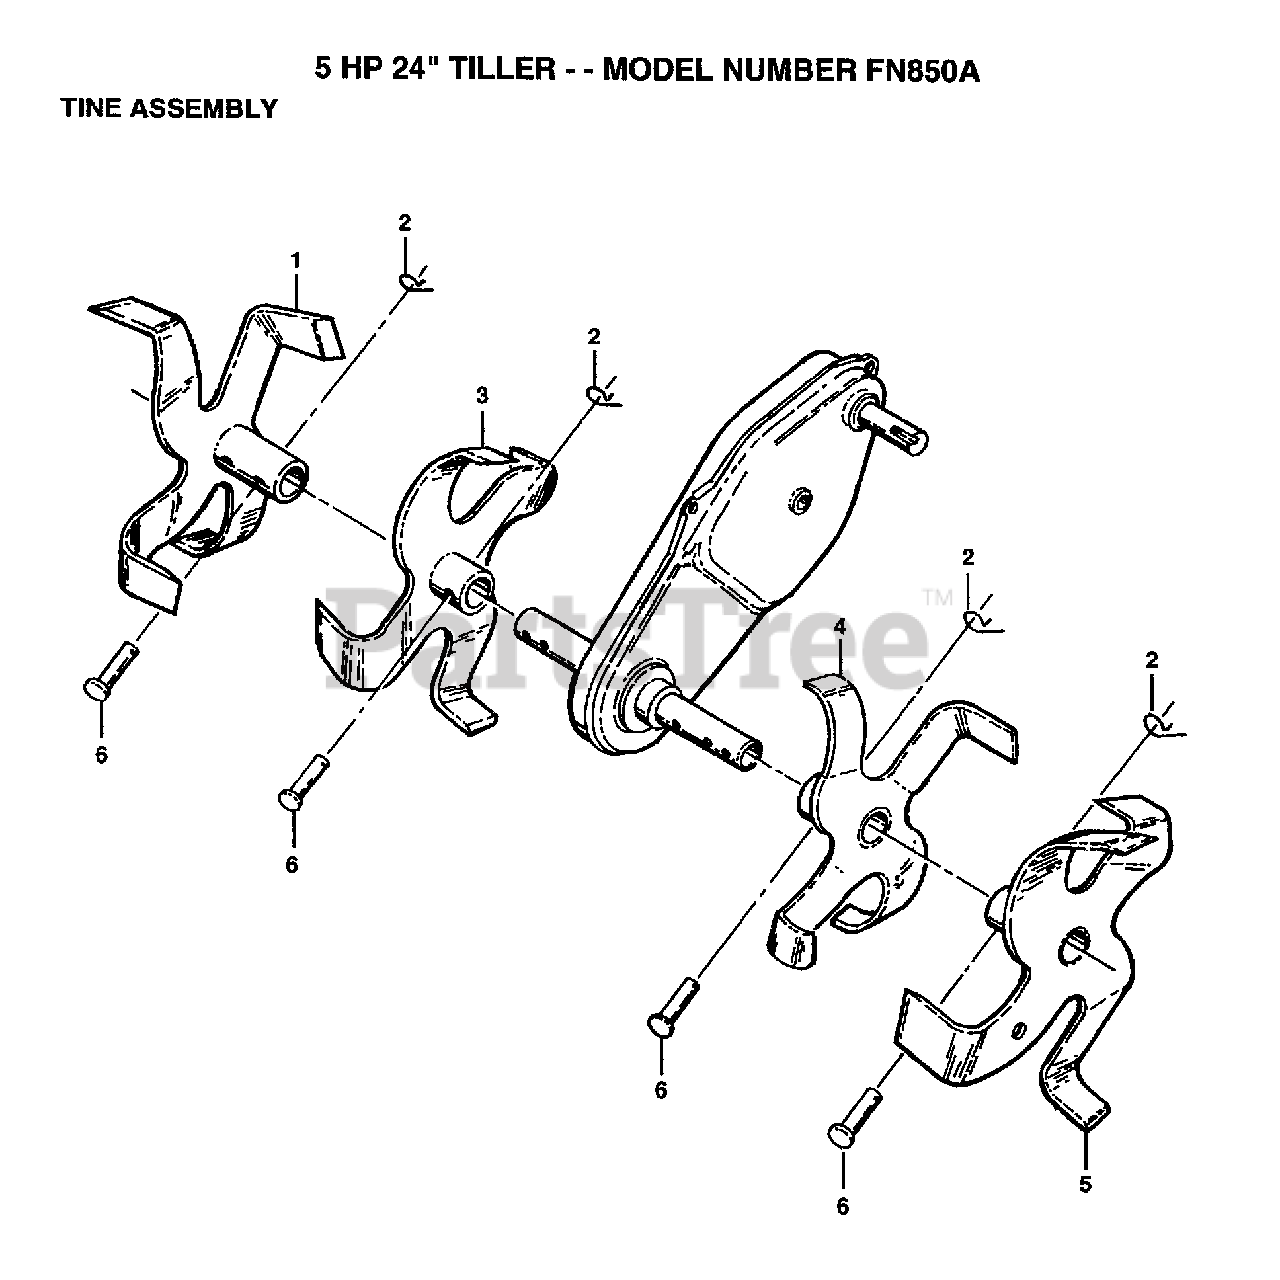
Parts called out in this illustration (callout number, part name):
1	TINE OUTER RH T
2	RETAINER.SPRING
4	TINE.INNER.LH
5	TINE.OUTER.LH.T
6	RIVET.PAN HD.1.75
